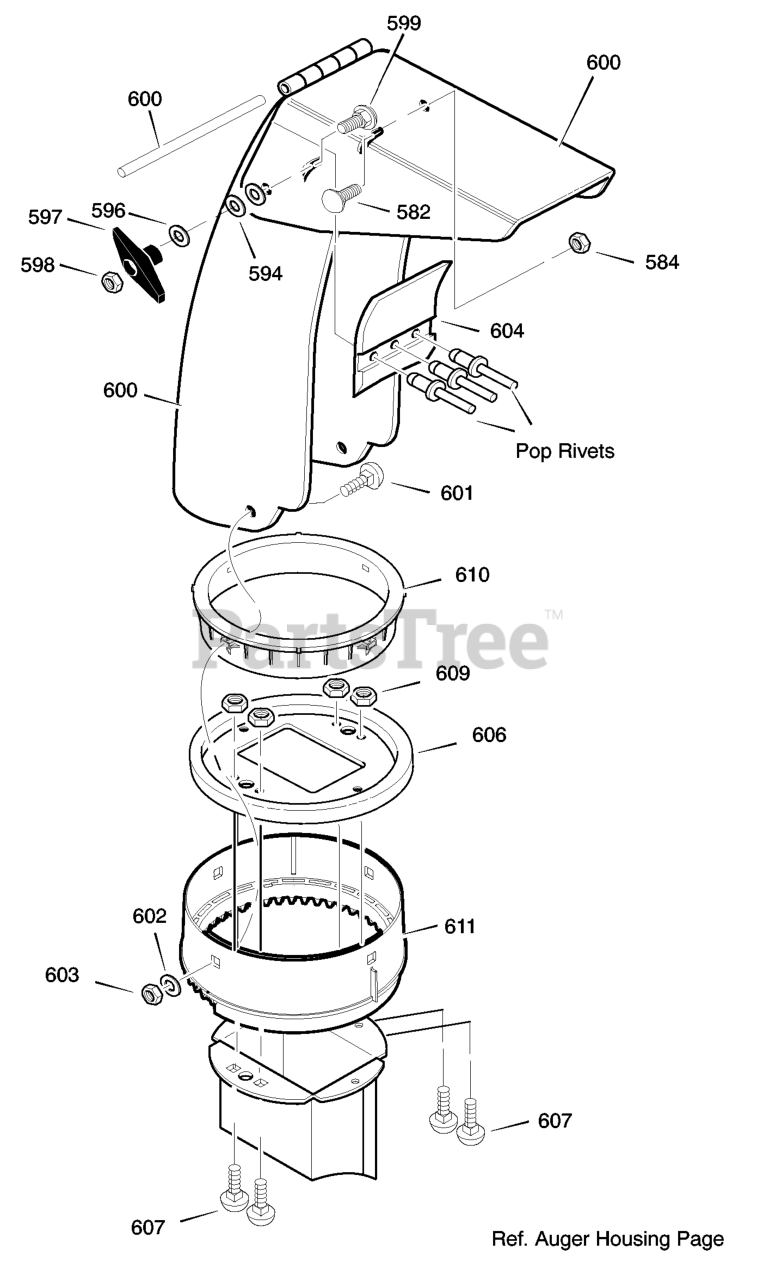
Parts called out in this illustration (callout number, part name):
582	BOLT, CARRIAGE 5/16-18 X.75
584	NUT, 5/16-18 REGHEX NYLOCK
594	WASHER, FLAT
596	WASHER, FLAT
597	KNOB, T 3.00
598	NUT, 5/16-18 REGHEX
599	BOLT, 5/16-18X1.00
600	CHUTE ASSEMBLY AND GUARD
601	BOLT, 5/16-18 X1.00
602	WASHER, FLAT
603	NUT, 5/16-18 HEXNYL
604	FLAP, CHUTE
606	CHUTE COLLAR
607	SCREW, 1/4-20 X 0.75
609	NUT, 1/4-20 HEX NYLOCK
610	RETAINER RING INNER
611	RETAINER RING OUTER
